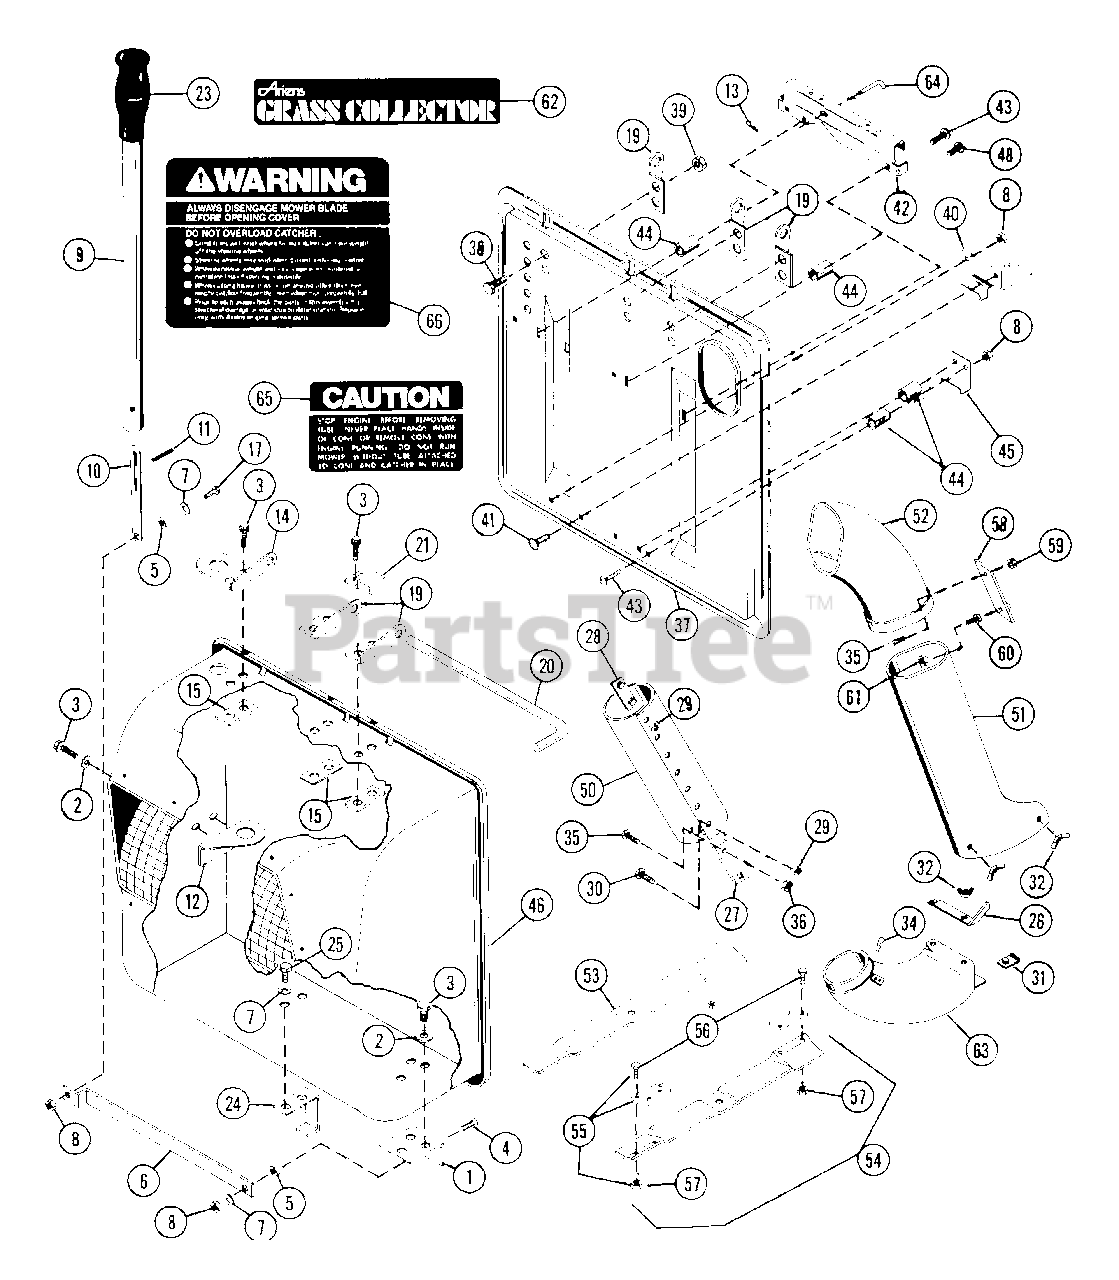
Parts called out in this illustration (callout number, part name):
1	LATCH PIVOT
2	WSHR-FL-STL .281X1.250X.048PL
3	BLT-SCRHFWH .25-20X.62 PL
4	BLT-RDHDSQNK .31-18X.75 SHT PL
5	SPACER
6	LATCH BAR
7	WSHR-FL-STL .390X.875X.18 PL
8	NUT-LK .312-18 GR A PL
9	TUBE .85 X 1.00 X 36.00
10	PLUNGER
11	PIN-ROLL .188X1.13
12	DUMP LEVER BRACKET
13	PIN-HAIR INT .08X.38X1.42 YWZC
14	LEVER GUIDE BRACKET
15	HINGE PLATE
16	SCR-TAP.250-20X.62 HWH BLK ZC
17	BLT-HEX .31-18X.75 PL GR2
20	HINGE PIN
21	HINGE PIN CLIP
23	GRIP
25	BLT-SERHFWH .31-18X.50 PL
32	NUT-WING W/INSERT .312 - 18
35	SCR-MCH 10-24X.62 SLRH PL
38	BLT-HEX .25-20X.50 PL GR2
39	NUT-LK-CTR .250-20 PL
40	LOWER MOUNTING BRACKET
41	BLT-RDHDSQNK .312-18X.62 PL
42	BRACKET
46	BUCKET ASSEMBLY
48	BLT-RDHDSQNK .312-18X.62 PL
51	LOWER COLLECTOR BOOT
55	SERVICE VANE PACKAGE
56	BLT-HEX .31-24X.75 GR8
57	NUT-LK TOP .312-24 PL GR C
58	LATCH STRAP
59	NUT-LK TOP 10-24 PL
61	NUT-LK 10-32 NY PL
62	ARIENS GRASS COLLECTOR DECAL
64	CLEVIS PIN
65	WARNING DECAL
66	CAUTION DECAL
